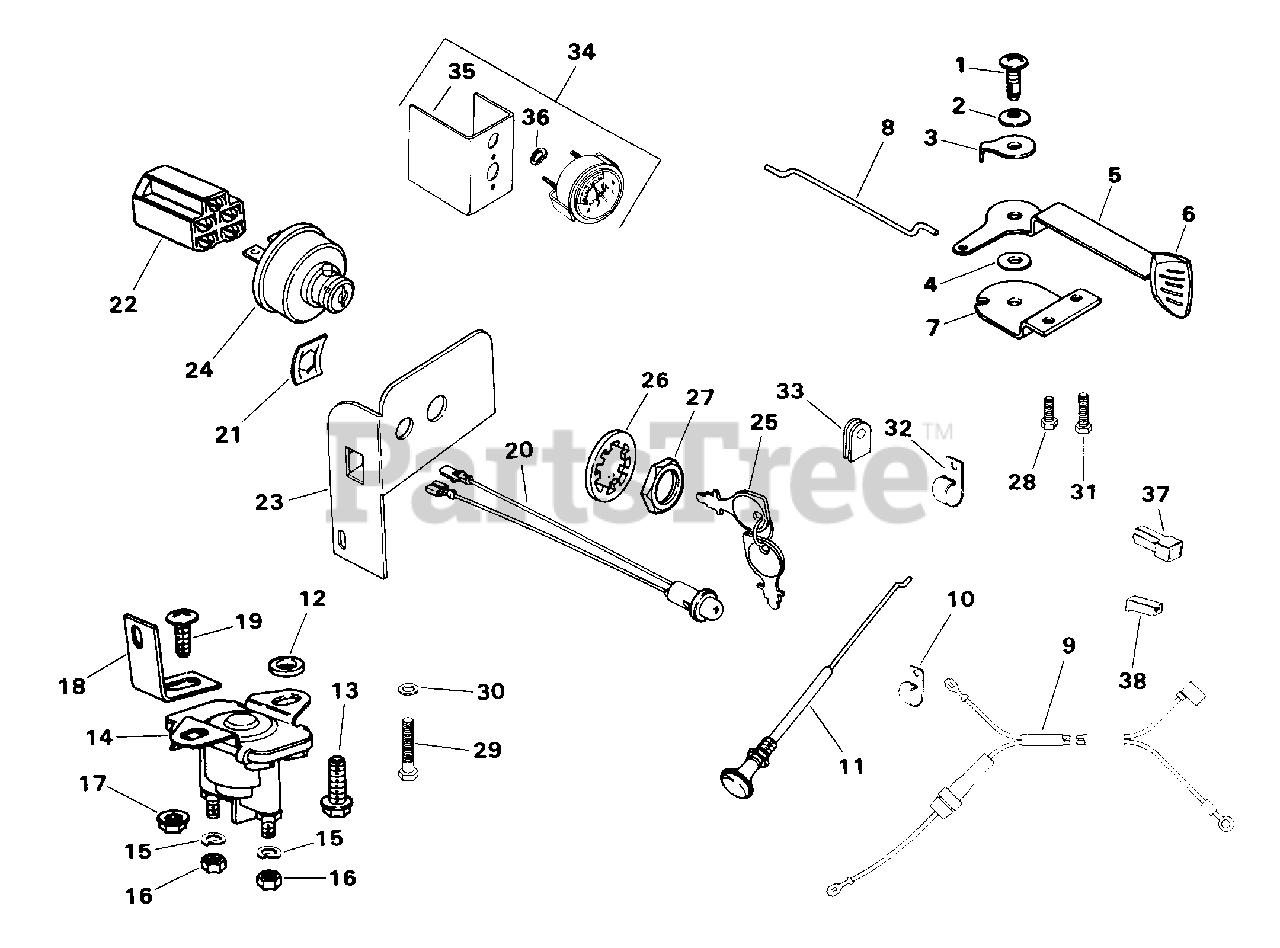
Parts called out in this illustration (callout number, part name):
1	SCREW, WSH HD 1/4-20X5/8" - DISCONTINUED
2	WASHER, SPRING 1/4"
4	WASHER - (#DSC)
5	LEVER - (#DSC)
8	LINKAGE - DISCONTINUED
9	HARNESS - (#DSC)
11	CABLE - DISCONTINUED
13	SCREW, WSH HD TAP 1/4-20X3/4" USE 25 086 100-S
14	SOLENOID - USE 25 435 02
15	WASHER, SPRING LOCK 1/4"
16	NUT, 1/4-20 GRADE 2 USE 25 100 20-S
17	PALNUT, 1/4-20
18	BRACKET - DISCONTINUED
22	CONNECTOR
23	PANEL - (#DSC)
24	SWITCH ASSY, KEY (KM)-USE 25 099 32-S
25	KEY, SET -USE 48 340 01-S
26	WASHER, INTERNAL TOOTH
27	NUT, KEY SWITCH
28	SCREW, WSH HD TAP #10-24X13/32" USE 25 086 109-S
29	SCREW, WSH HD TAP 1/4-20X7/16" USE 25 086 106-S
30	WASHER - (#DSC)
